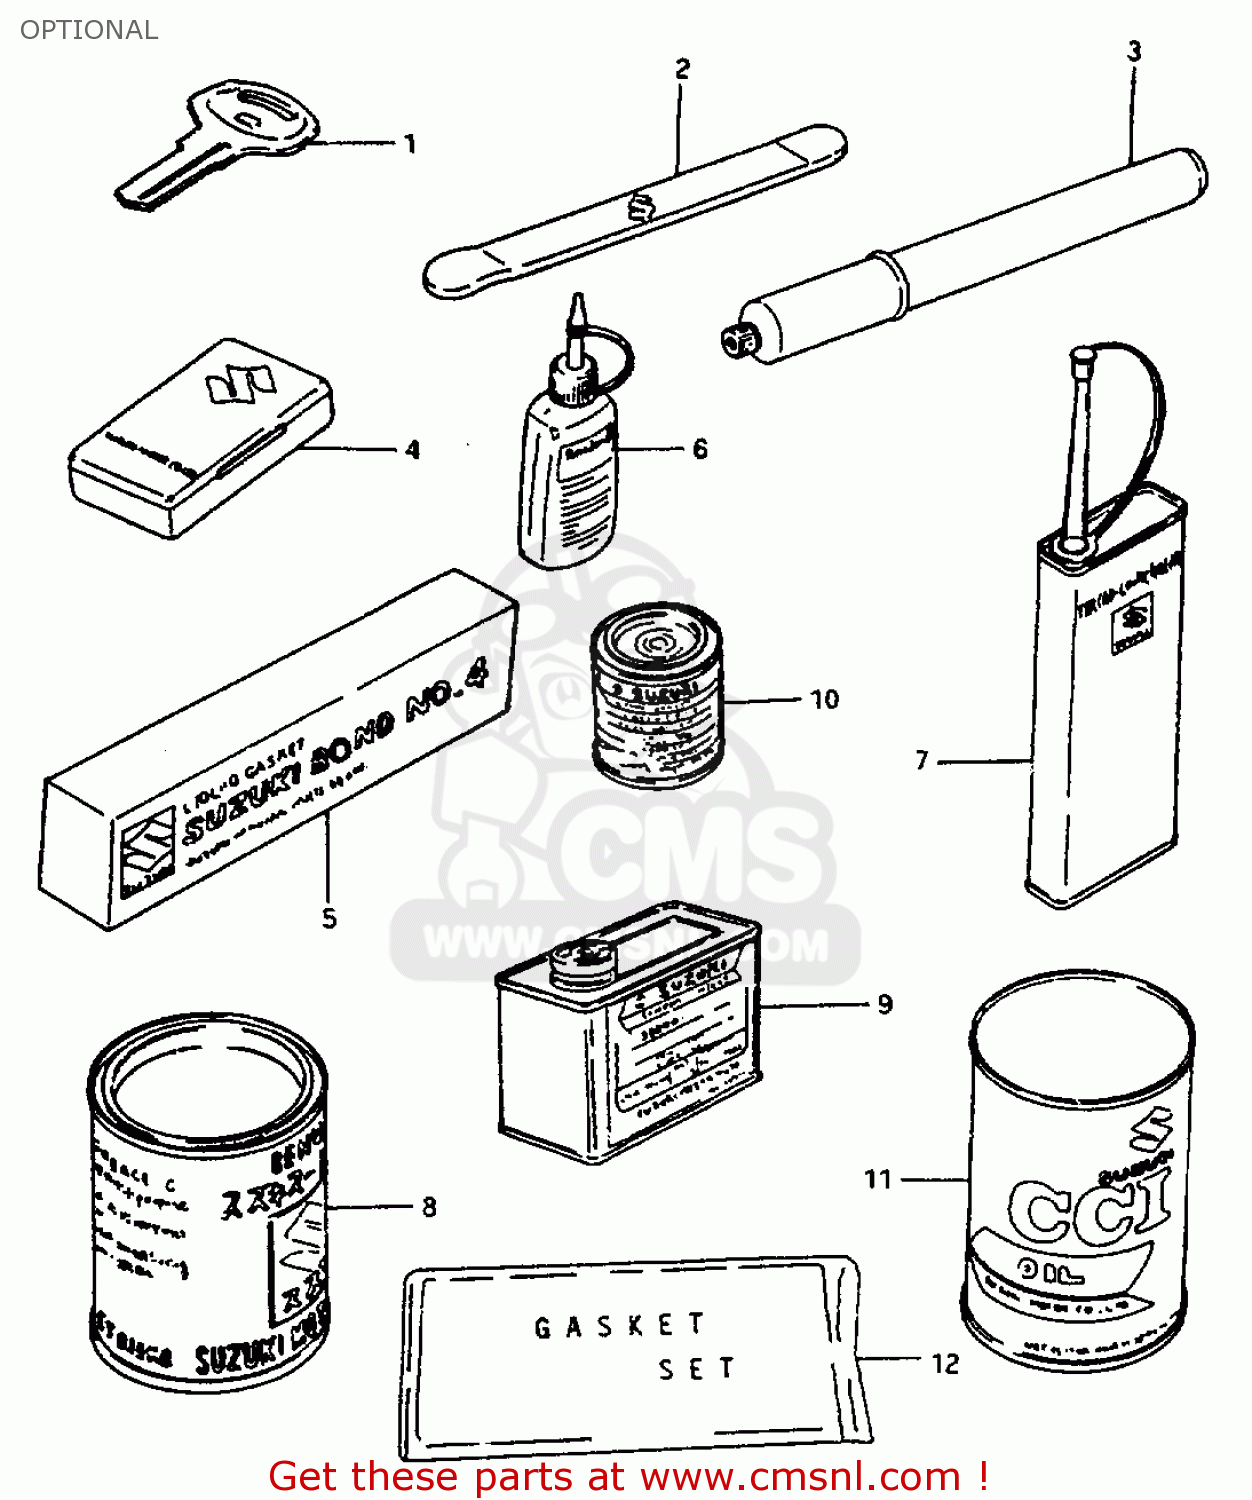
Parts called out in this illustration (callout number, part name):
1	KEY,BLANK
2	LEVER,TIRE
3	INFLATOR, AIR
4	TUBE REPARING TOOL
5	BOND 1104
6	THREAD LOCK NO.1303B PURPL 50G
7	THREAD LOCK NO.1401 CLEAR 200G
8	GREASE(C)EP2 LITHIUM 150G
9	PAINT (BLACK)
10	PAINT,BLACK
11	CCI OIL
12	GASKET SET (MCA)
